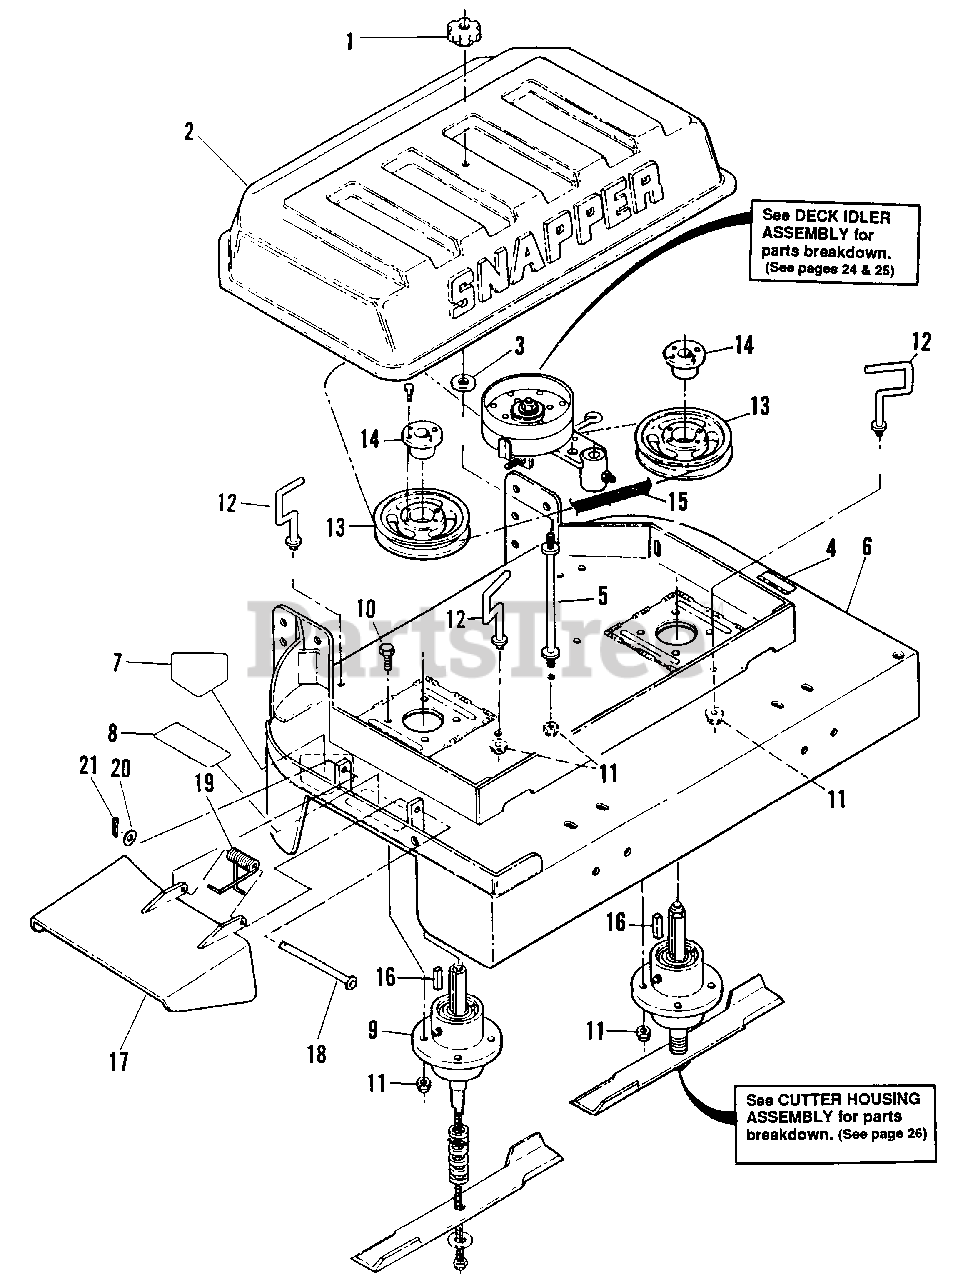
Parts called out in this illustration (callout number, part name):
1	KNOB
2	HOOD, Model PMA7360
3	BUSHING
4	DECAL, "Caution"
5	STUD, Hood Mount
6	DECK WELDMENT, 36"
7	DECAL, "Danger"
8	DECAL, "Caution"
9	ASSEMBLY, Cutter Housing
10	SCREW, 3/8-16 x 1-1/4" Hex Head Cap
11	NUT, 33/8-16 Hex Nyloc
12	GUIDE, Belt
13	PULLEY, Cutter Blade Drive
14	BUSHING, Taperlock
15	BELT, 36" Deck
16	KEY, Spindle
17	DEFLECTOR, 36" Chute
18	ROD, Chute Pivot
19	SPRING, Chute
20	WASHER, 5/16" Flat
21	PIN, 3/32" x 1" Cotter
